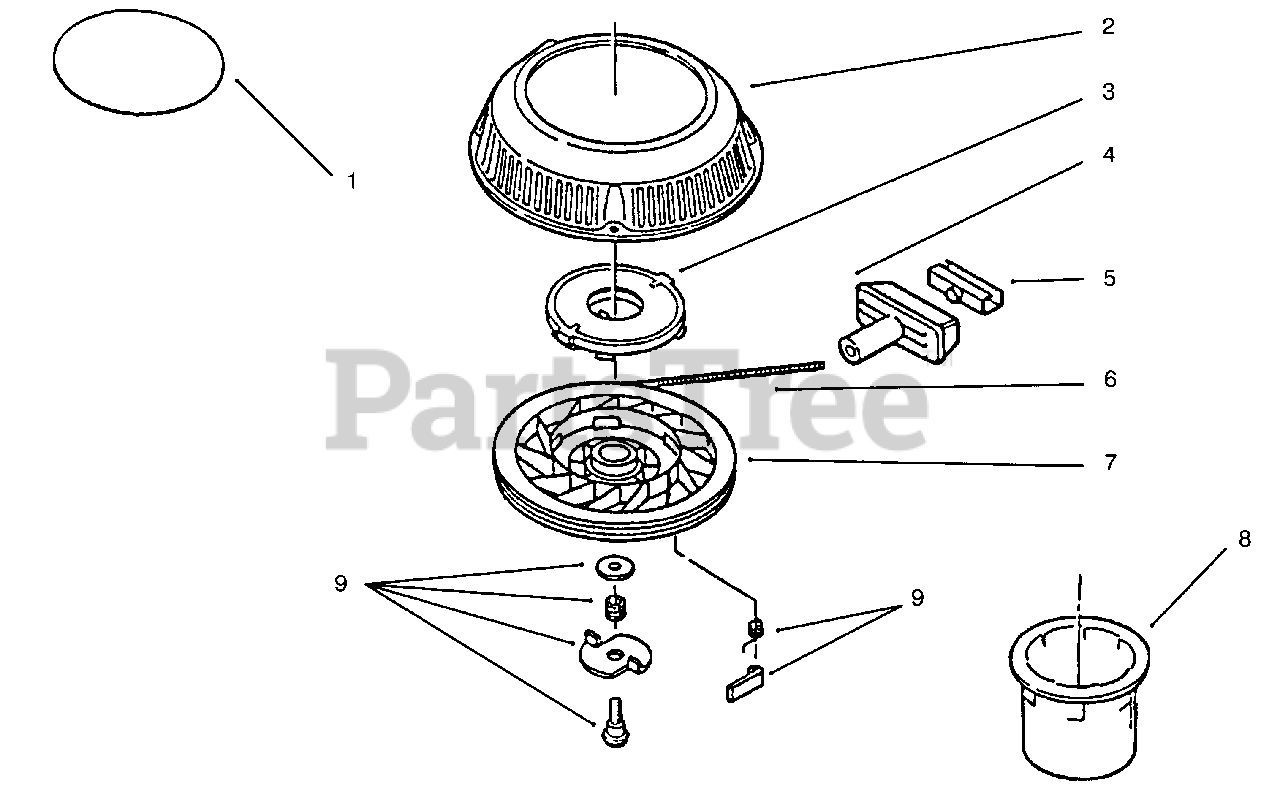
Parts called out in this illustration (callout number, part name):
1	Decal-Recoil (Hand Push)
2	Starter Housing & Shaft
3	Spring & Keeper
4	Handle-Starter
5	Clip-Rope
6	Rope
8	Hub-Starter
9	Kit-Dog
